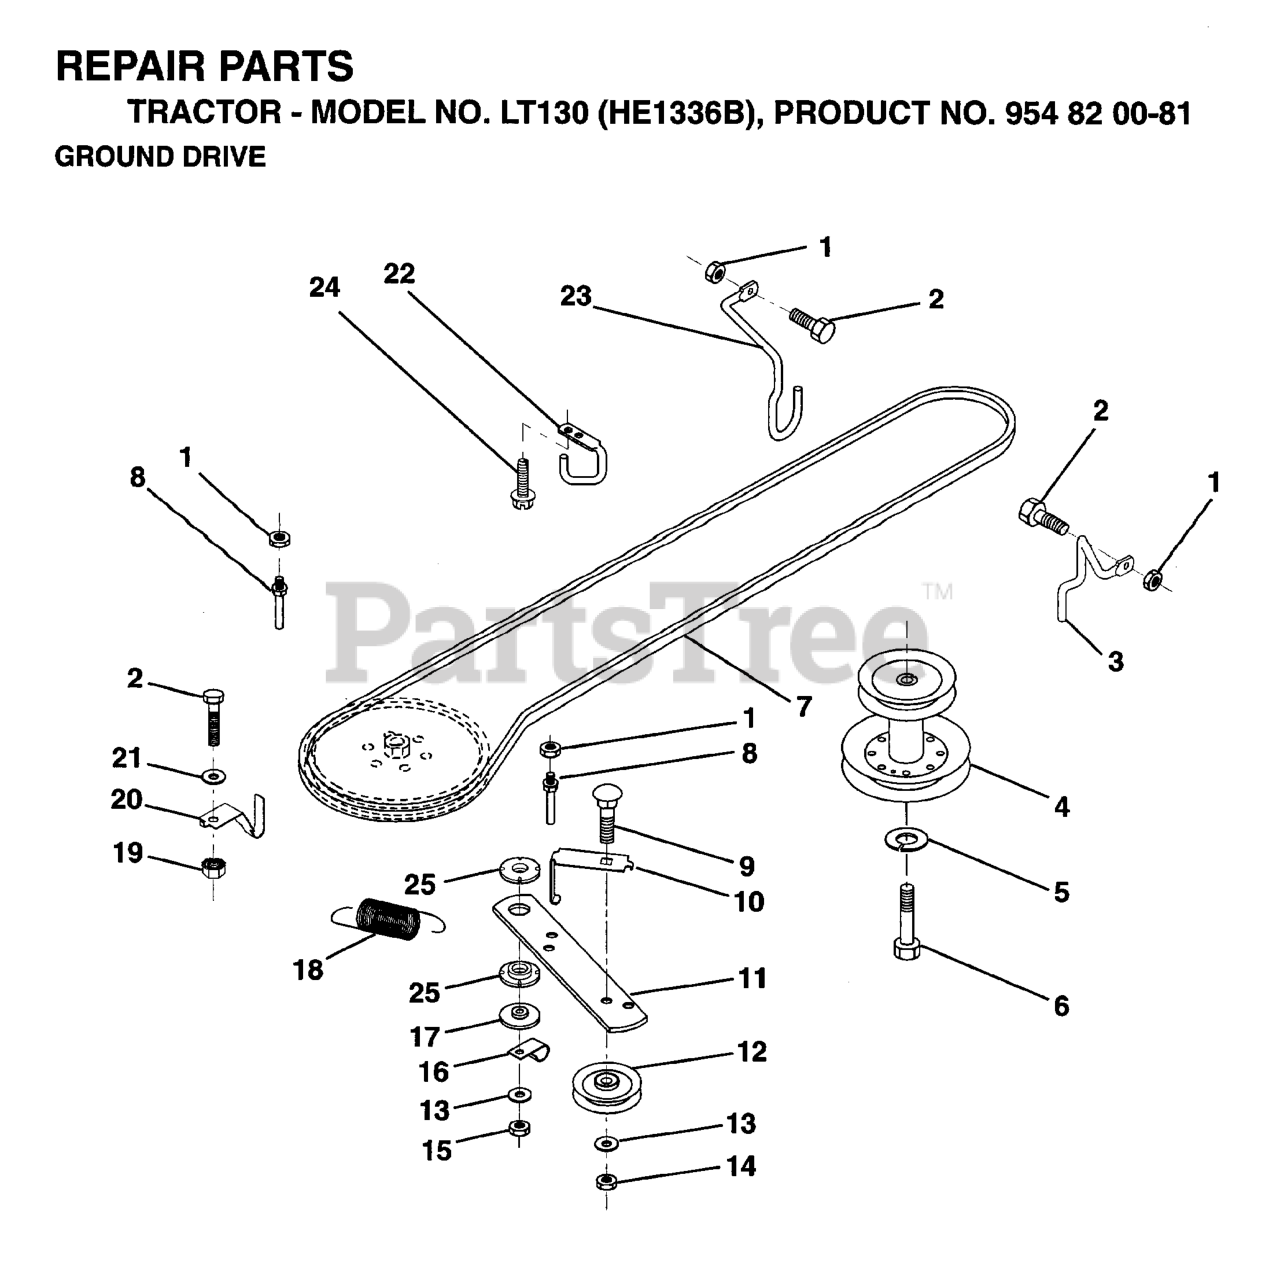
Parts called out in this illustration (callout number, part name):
1	LOCKNUT
2	BOLT
3	KEEPER/MOWER DRIVE RH
4	PULLEY.ENGINE.36/38 LR
5	LOCKWASHER
6	Bolt, Hex Hd. 7/16-20 UNF Grade 5
7	BELT
8	KEEPER,DRIVE BELT
9	Bolt, Carriage 3/8-16 UNC x 1-1/2
10	KEEPER.BELT.GROUND.DRIVE.IDLER
11	ARM, GROUND DRIVE CLUTCH
12	PULLEY.IDLER.FLAT
13	WASHER
14	LOCKNUT
16	CLIP,INSULATOR
17	SPACER, RETAINER
18	SPRING.EXTENSION
19	NUT
20	KEEPER-T/A GROUND DRIVE BELT
21	Washer 11/32 x 5/8 x 16 Ga SD
22	KEEPER,FRA DR BEL
23	KEEPER-MOWER DRIVE LH
24	SCREW
25	BUSHING NYLON COLLERED
